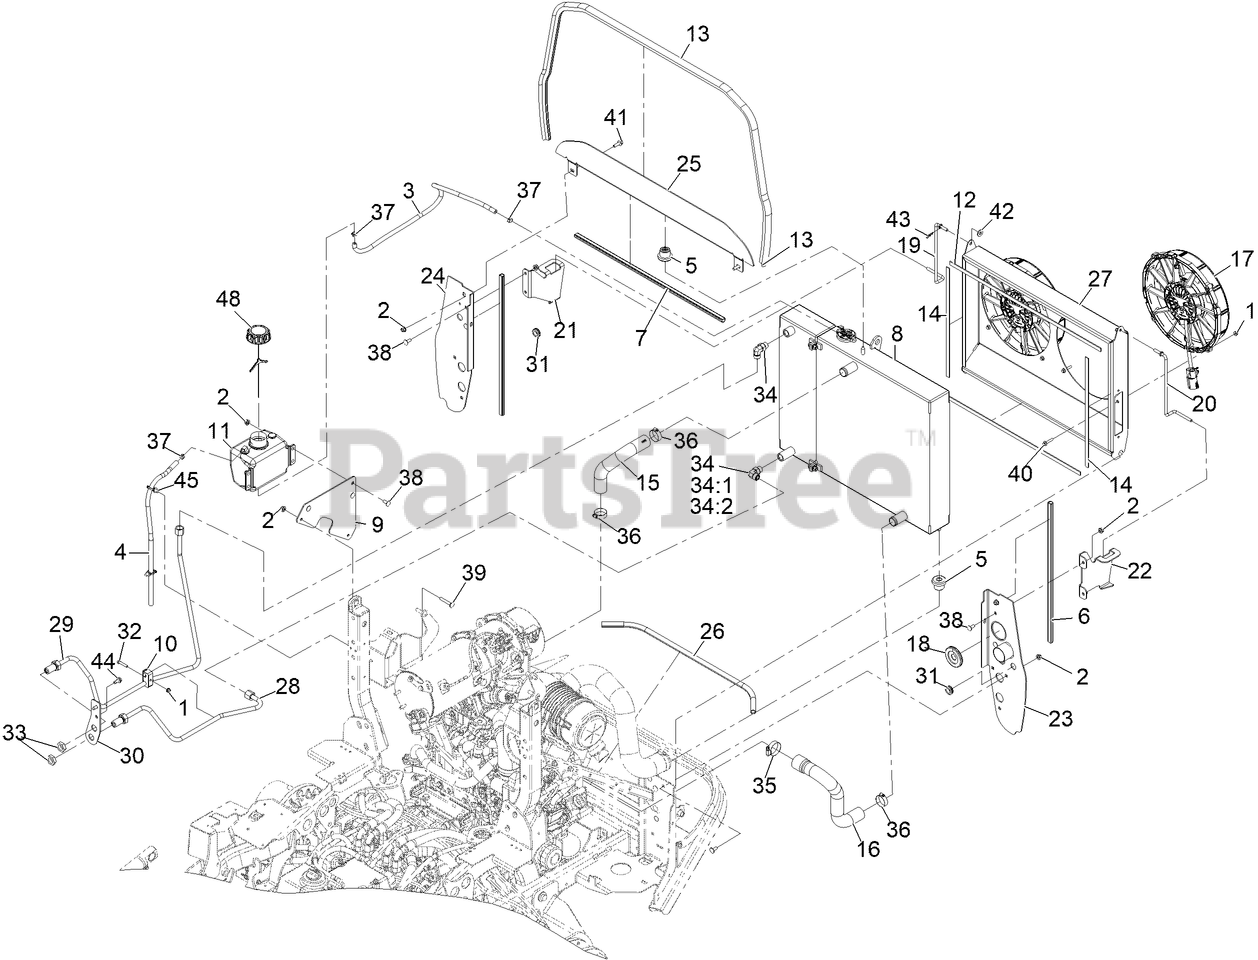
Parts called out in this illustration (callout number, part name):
1	NUT-HF
2	NUT-HF, NI
3	HOSE-FUEL
4	HOSE-FUEL
5	MOUNT-ISOLATOR
6	SEAL-BULB
7	SEAL-BULB
8	COOLING ASM
9	BRACKET-BOTTLE
10	FOAM-ADHESIVE BACKED
11	CLAMP-TWIN
12	TANK-OVERFLOW, W/CAP
13	SEAL-BULB
14	FOAM-ADHESIVE BACKED "
15	HOSE-RADIATOR, UPPER
16	HOSE-RADIATOR, LOWER
17	FAN-12", 12V, ELECTRIC, REVERSING
18	GROMMET-SPLIT, 2.38 GD X 0.14 GW X 0.82
19	WIRE FORM-FAN SHROUD, R
20	WIRE FORM-FAN SHROUD, L
21	BRACKET-SHROUD LATCH RIGHT
22	BRACKET-SHROUD LATCH LEFT
23	SUPPORT-RADIATOR, LH [BLACK]
24	BRACKET-COOLING, RH
25	BRACKET-COOLING, TOP
26	SEAL-BULB
27	FAN SHROUD
28	HYDRAULIC TUBE ASM
29	HYDRAULIC TUBE ASM
30	BRACKET-BULKHEAD
31	GROMMET
32	SCREW-HH
33	NUT-BULKHEAD
34	FITTING-ELBOW, 90 DEG
34:1	O-RING
34:2	O-RING
35	CLAMP-HOSE
36	CLAMP-HOSE
37	CLAMP-HOSE
38	SCREW-CARR
39	BOLT-CARR
40	SCREW-HHF
41	SCREW-HHF
42	WASHER-FLAT
44	SCREW-HWHTF
45	CLIP-TIE
48	CAP-W/TETHER
